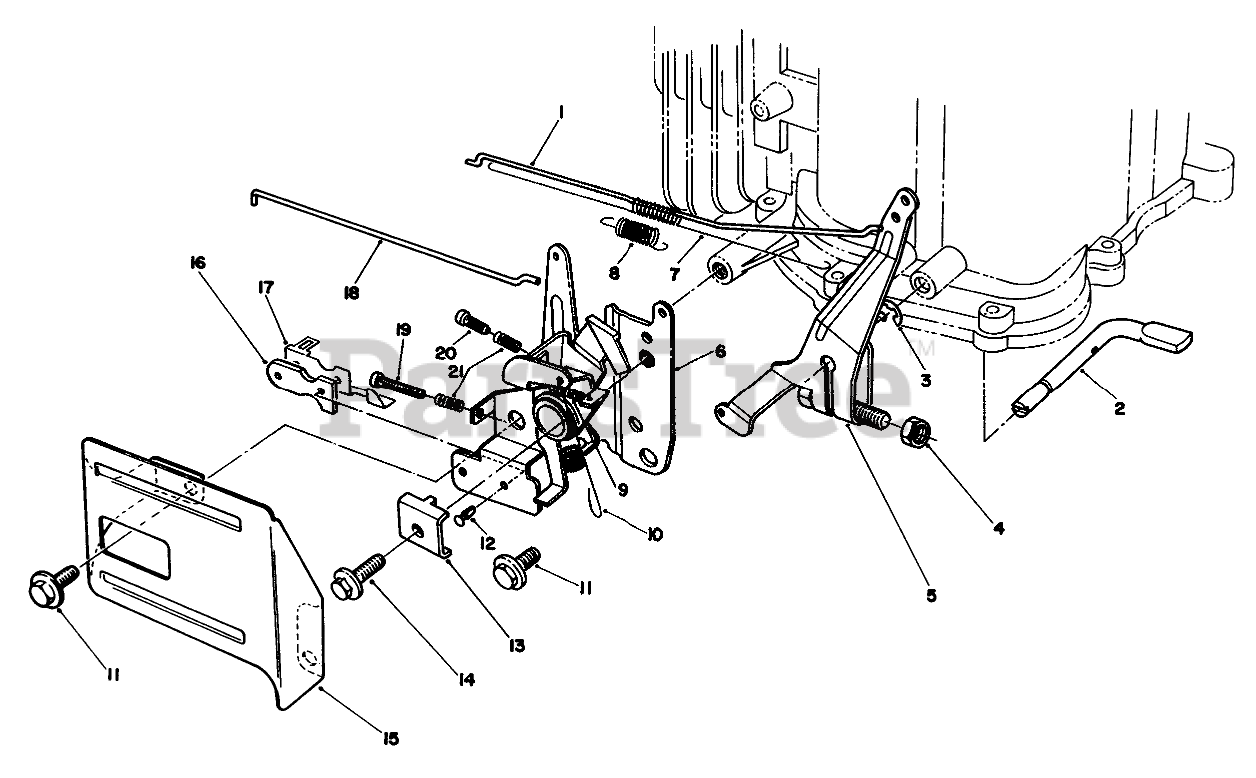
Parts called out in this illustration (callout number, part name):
1	Rod-Carburetor
2	SHAFT
3	E-RING
4	Nut
5	ARM ASM
6	THROTTLE
7	SPRING
8	SPRING
9	SPRING
10	SPRING
12	RIVET
13	CLAMP-CABLE
15	THROTTLE GUARD
16	INSULATOR-KILL SWITCH
17	TERMINAL-KILL SWITCH
18	Rod-Choke
19	SCREW
20	SCREW
21	Spring
